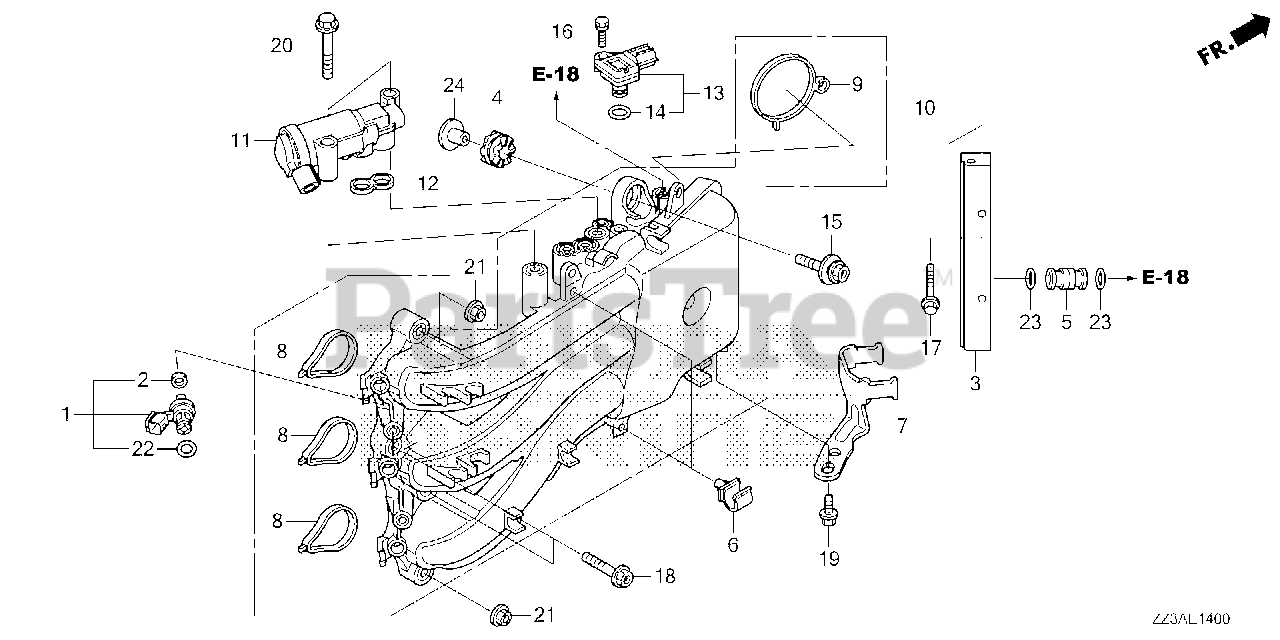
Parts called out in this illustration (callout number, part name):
1	INJECTOR ASSY., FUEL
2	RING, SEAL
3	LINE, FUEL
4	GROMMET, VAPOR SEPARATOR
5	JOINT, FUEL PIPE
6	CLAMP B, FUEL TUBE
7	STAY, FUEL STRAINER
8	GASKET, IN. MANIFOLD
9	GASKET, THROTTLE BODY
10	MANIFOLD, INLET
11	VALVE ASSY., ELECTRONIC AIR CONTROL
12	GASKET, ELECTRONIC AIR CONTROL VALVE
13	SENSOR ASSY., MAP
15	BOLT-WASHER (8X35)
16	BOLT-WASHER (5X18)
17	BOLT, FLANGE (6X32)
18	BOLT, FLANGE (8X32)
19	BOLT, FLANGE (6X12)
20	BOLT, FLANGE (8X45)
21	NUT, FLANGE (8MM)
22	O-RING (7.3X2.2)
23	O-RING (7.8X1.9) (ARAI)
24	COLLAR (8.5X14.5)
